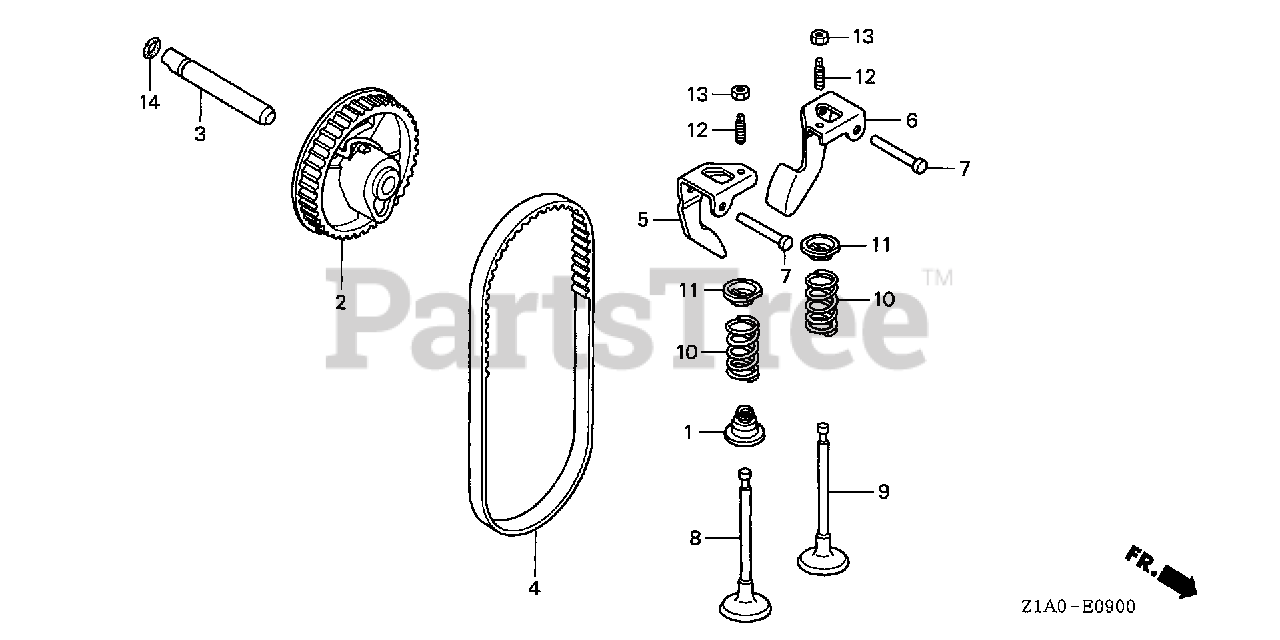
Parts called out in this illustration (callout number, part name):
1	SEAL, VALVE STEM
2	PULLEY, CAMSHAFT
3	SHAFT, CAM PULLEY
4	BELT, TIMING (84HU7 G-200)
4	BELT, TIMING (84HU6 G-200)
5	ARM, IN. VALVE ROCKER
6	ARM, EX. VALVE ROCKER
7	SHAFT, ROCKER ARM
8	VALVE, IN. (TECHNOSTAR)
9	VALVE, EX. (L8E)
9	VALVE, EX. (C8E)
10	SPRING, VALVE
11	RETAINER, VALVE SPRING
12	SCREW, TAPPET ADJ.
13	NUT, TAPPET ADJ.
14	O-RING (6.8X1.9) (ARAI)
